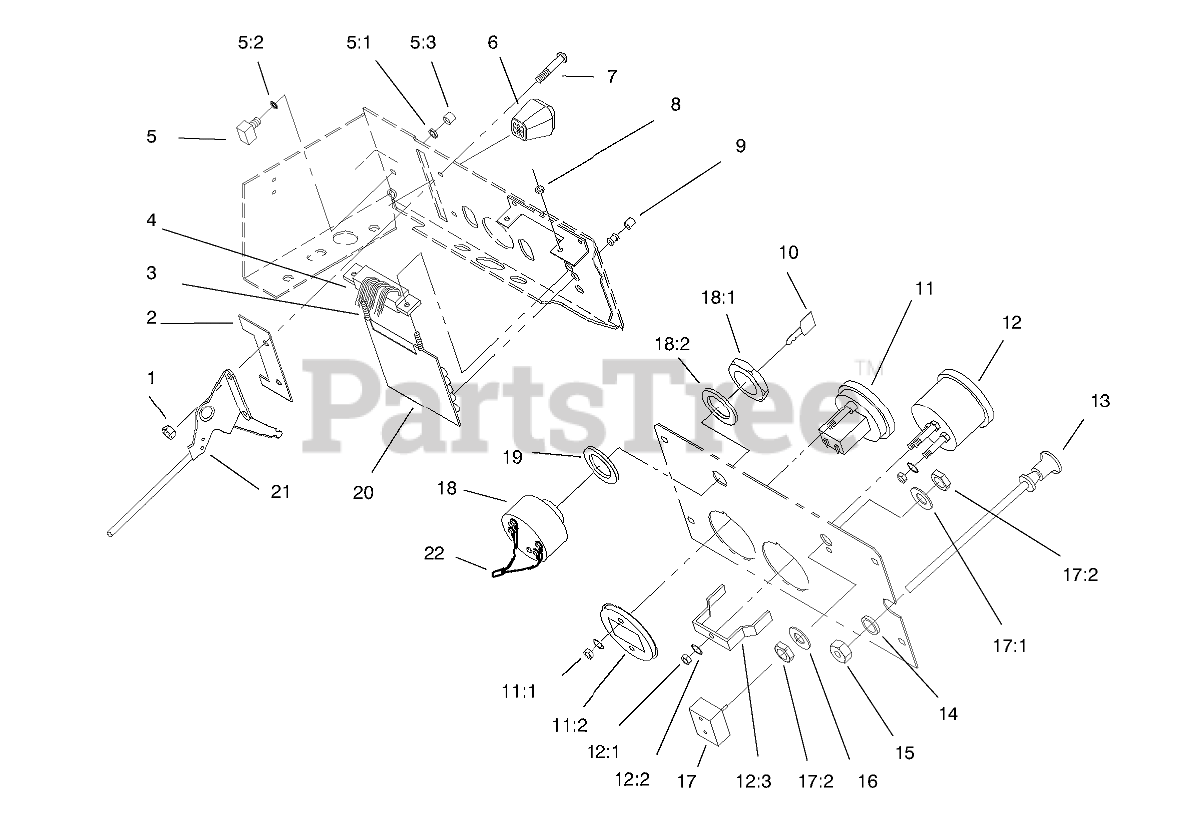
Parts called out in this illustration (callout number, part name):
1	Nut
2	STOP-THROTTLE
3	Screw
4	P.C.-BOARD HARNESS
5	SWITCH-PUSH BUTTON
5:1	NUT F/W 116796
5:2	Washer
5:3	BUTTON F/W 116796
7	SCRW-PHC
8	NUT-HEX
9	ASSY LENS & BUSHING
10	KEY-IGNITION
11	Hourmeter
11:1	NUT-HEX, KEPS
11:2	Retainer
12	VOLTMETER
12:1	NUT-HEX
12:2	WASHER-LOCK
12:3	CLAMP-MOUNTING
13	CONTROL CHOKE
14	WASHER-FLAT
15	NUT-HEX PALNUT
16	WASHER
17	SWITCH-LIGHTS
17:1	TAB-WASHER
18	KEY SWITCH ASM
18:2	WASHER-LOCK
19	WASHER
20	Board-Pc
21	CONTROL-THROTTLE
